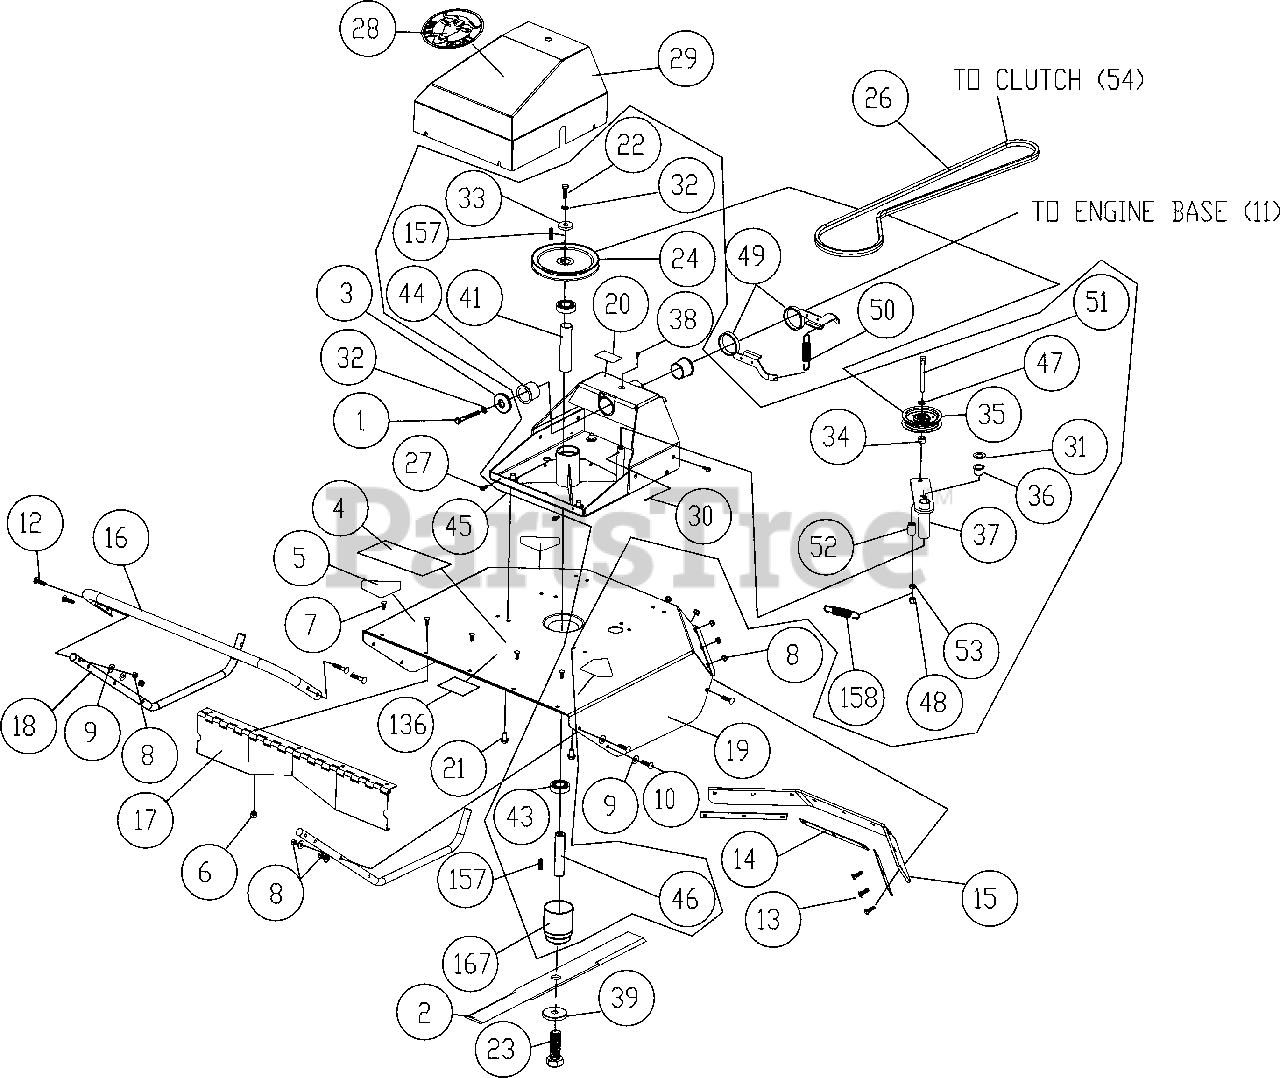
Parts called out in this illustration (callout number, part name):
1	SCREWCAP 3/8-24 X 1” HCS GR. 8
2	BLADE 26” FLAT BC26
3	WASHER DECK RETAINNG
4	LABEL BADGING BC26 HYDRO
5	LABEL DANGER
6	NUT LOCK 1/4-20 ZP
7	BOLT CARRIAGE 1/4-20 X 3/4” HCS ZP
8	NUT LOCK 5/16-18 ZP
9	WASHER 5/16 FLAT
10	SCREWCAP 5/16”-18 X 1 1/2 HCS ZP
12	CARRIAGE BOLT 5/16”-18 X 1 3/4”
13	CARRIAGE BOLT 5/16”-18 X 1”
14	PLATE CLAMP SKIRTING BC26
15	DEFLECTOR RUBBER
16	BAR GUARD BC26
17	HINGE DEFLECTOR BC26
18	SKID BC26
19	DECK BC26 WA W/LABELS
20	LABEL DANGER GUARD
21	SCREW SER HEX WASHER FLNG
22	SCREWCAP 3/8”-16 X 1 1/4” HCS ZP
23	SCREWCAP 9/16”-18 X 1 3/4” GR 8
24	PULLEY 7” OD X 1.000 BORE
26	BELT 6972 POWERATED
27	SCREW SELT TAP 1/4-20 X 5/8” HWH TYPE F
28	LABEL PRODUCT DECAL LG CIRCLE
29	COVER BELT DECK WA BC26 W/LABEL
30	PIN COTTER 1/8” X 1”
31	WASHER .765 ID X 1.25 OD X .06 THK
32	WASHER LOCK 3/8 S/T MED
33	WASHER 1.5 OD X .453 ID X .25 THK
34	TUBE PIVOT IDLER VQ
35	PULLEY IDLER 4.00 OD X 3/8” BORE
36	BUSHING PIVOT FRAME AE
37	ARM IDLER DECK WA BC
38	ZERK FITTING GREASE
39	WASHER BLADE BC26
41	SPACER SPINDLE BEARING BC26
43	BEARING 1.00” SEALED PRESS IN
44	BUSHING 1.500 ID X 1.5 LONG FLANGED
45	BRACKET DECK MOUNT WA BC26 W/LABEL
46	SHAFT BLADE BC26
47	WASHER 3/8” SAE
48	NUT LOCK 3/8-16 HEX
49	ARM RTN WA BC26
50	SPRING LIFT ASSIST TENSION
51	SCREWCAP 3/8”-16 X 3 3/4” HCS ZP
52	BUSHING PIVOT LIFT
53	NUT LOCK 3/8”-16 LT WT TH ZP
136	LABEL WARNING FLYING DEBRIS
157	KEY 1/4 SQ. X 0.75”
158	SPRING IDLER BC
167	ADAPTER BLADE WA BC26
